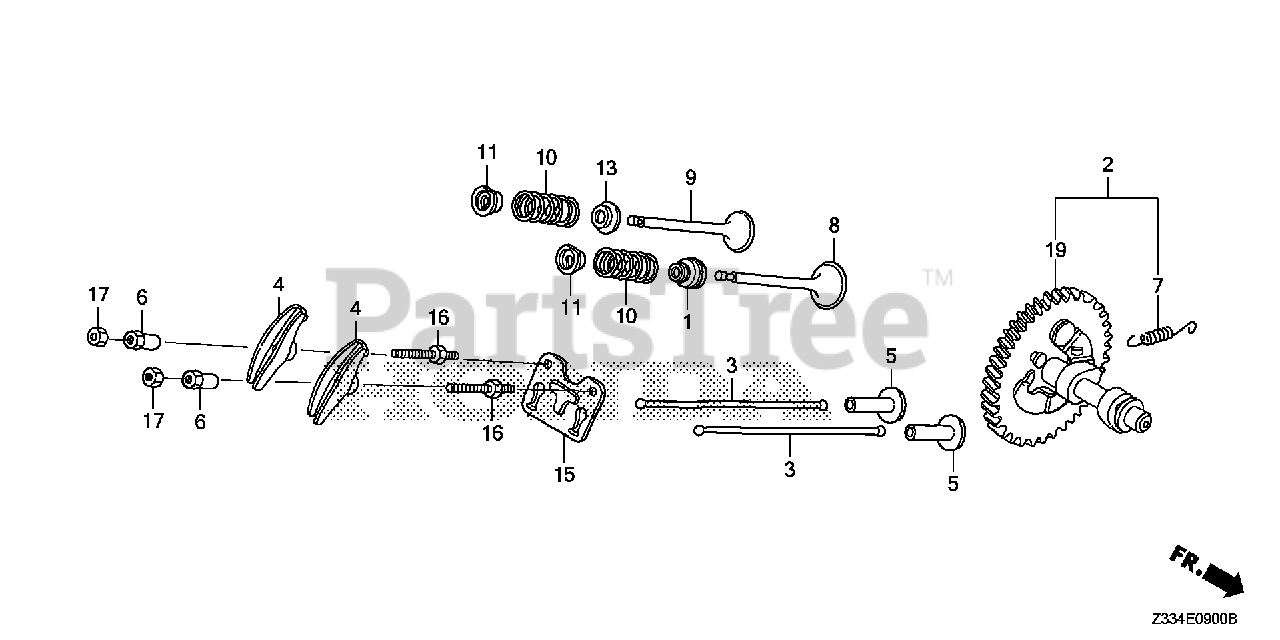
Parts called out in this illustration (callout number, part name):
1	SEAL, VALVE STEM
4	ARM, VALVE ROCKER
5	LIFTER, VALVE
6	PIVOT, ROCKER ARM
8	VALVE, IN.
9	VALVE, EX.
10	SPRING, VALVE
11	RETAINER, IN. VALVE SPRING
13	SEAT, VALVE SPRING
15	GUIDE, PUSH ROD
16	BOLT, PIVOT (8MM)
17	NUT, PIVOT ADJUSTING
19	CAMSHAFT (STD) (PRESS FIT CAM)
